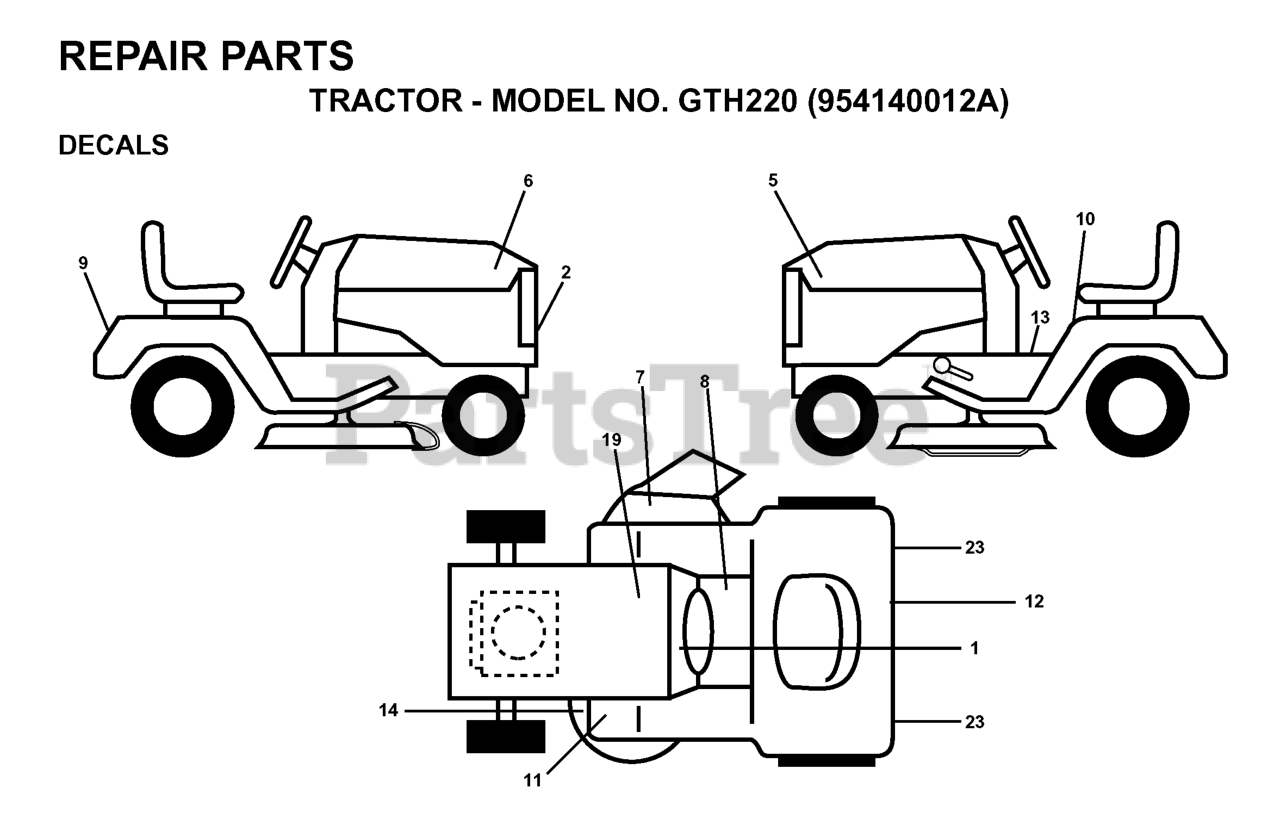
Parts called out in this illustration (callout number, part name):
2	DECAL.GRILLE.HUSQ
7	DECAL WARNING (ENGLISH/FRENCH)
8	DECAL PARK BRAKE
9	Decal, Fender
10	DECAL FENDER DANGER
19	DECAL, BATTERY DANGER
23	REFLECTOR-TAIL YT
